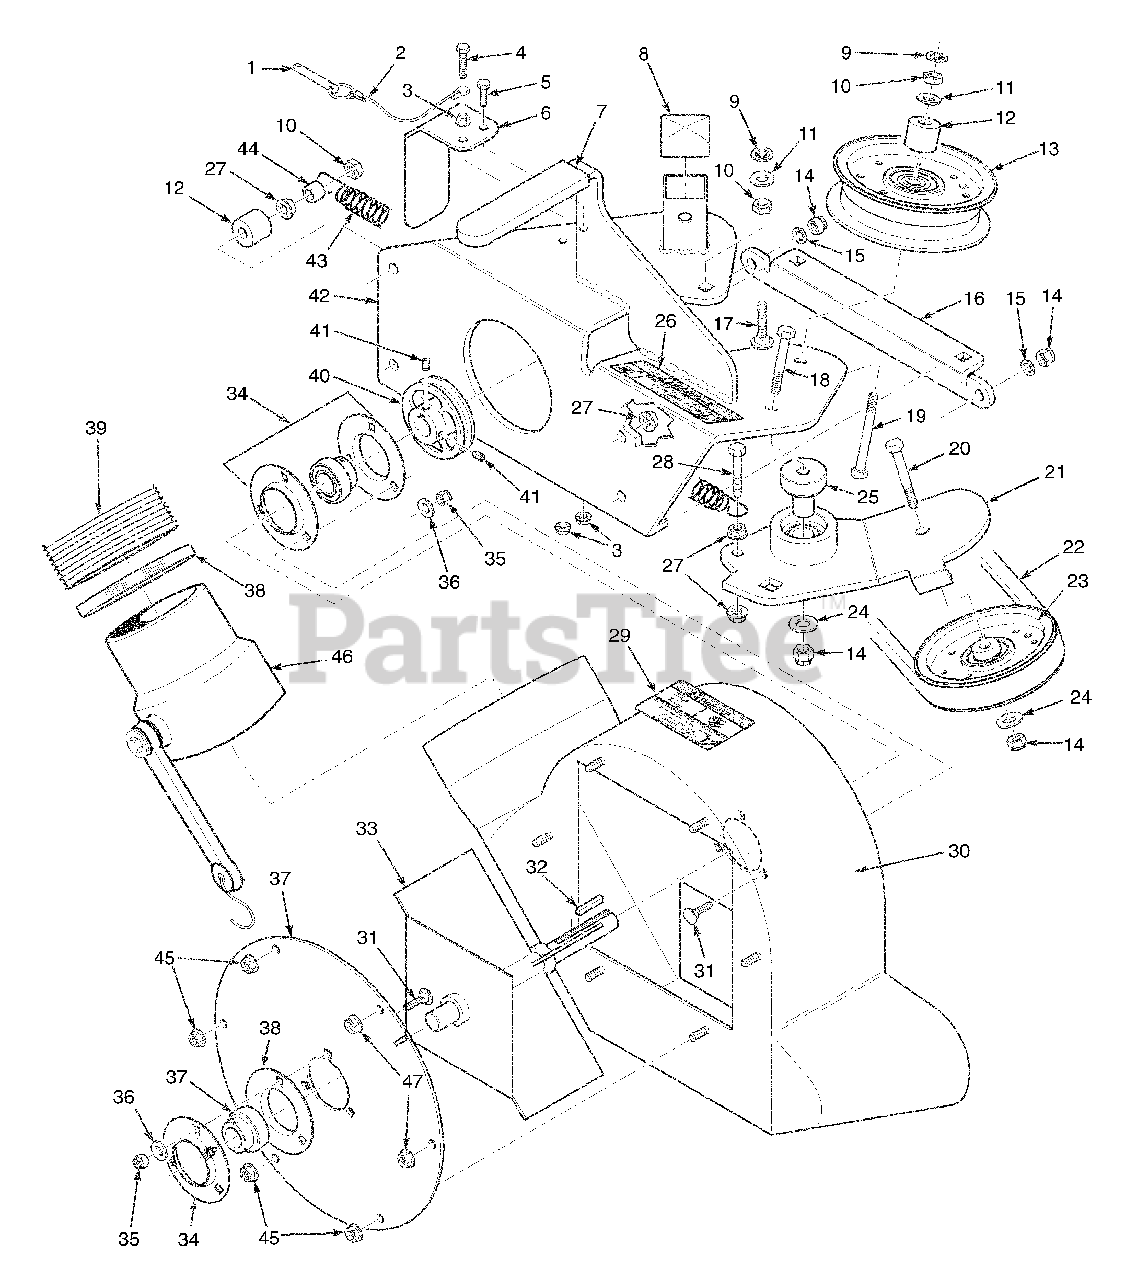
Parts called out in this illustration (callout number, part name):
1	Pin, Ring 2-1/4" Long
2	Lanyard, Deck Height Pin
3	Nut, Serr. Flange 1/4-20
4	Bolt, Hex Head 1/4-20 x 1-1/4"
5	Bolt, Hex Head 1/4-20 x 3/4"
6	Belt Cover, Rear
7	Grip, Blower Lever
8	Cap, Square
9	Nut, Push On 3/8 Thread
10	Lock Nut, 3/8-16
11	Flatwasher, 3/8-.391 x .938 x .105
12	Spacer
13	Pulley, Idler 4" Dia. - 61" Cutter Deck
14	Nut, Elastic Stop 3/8-16
15	Lockwasher, 3/8-16
16	Plate, Catch Mounting
17	Bolt, Carr. 3/8-16 x 1-1/2"
18	Bolt, Hex Head 3/8-16 x 3" - 52"
19	Bolt, Hex Head 3/8-16 x 3-1/2"
20	Bolt, Hex Head 3/8-16 x 1-3/4"
21	Idler Arm Assembly, GC-STT 52"
22	Belt, GC-STT 52"
23	Pulley, 3" O.D., GC-STT 52"
24	Washer, 3/8 Hardened
25	Pivot, Idler - 61"
26	Decal, Belt Cover
27	Nut, Serr. Flange 3/8-16
28	Bolt, Hex Head 3/8-16 x 1-1/2 Gr. 8
29	Decal, Danger
30	Blower Housing Assembly
31	Bolt, Carr. 5/16-18 x 3/4" Gr. 5
32	Key, 1/4 x 1/4 x 1-1/2"
33	Fan Weldment
34	Bearing Assembly
35	Nut, Elastic Stop 5/16-18
36	Flatwasher, 5/16-.344 x .688 x .065
37	Cover, Blower Housing
38	Clamp, 8-5/8" Max Dia.
39	Hose, 8.00" Dia. x 56.00" Long
40	Pulley, 4-3/4" O.D. - 1" Bore
41	Set Screw, 5/16-18 x 3/8"
42	Frame, Blower Mount - 61"
43	Spring, Main Drive
44	Spacer
45	Nut, Serr. Flange 5/16-18
46	Adapter w/Strap
